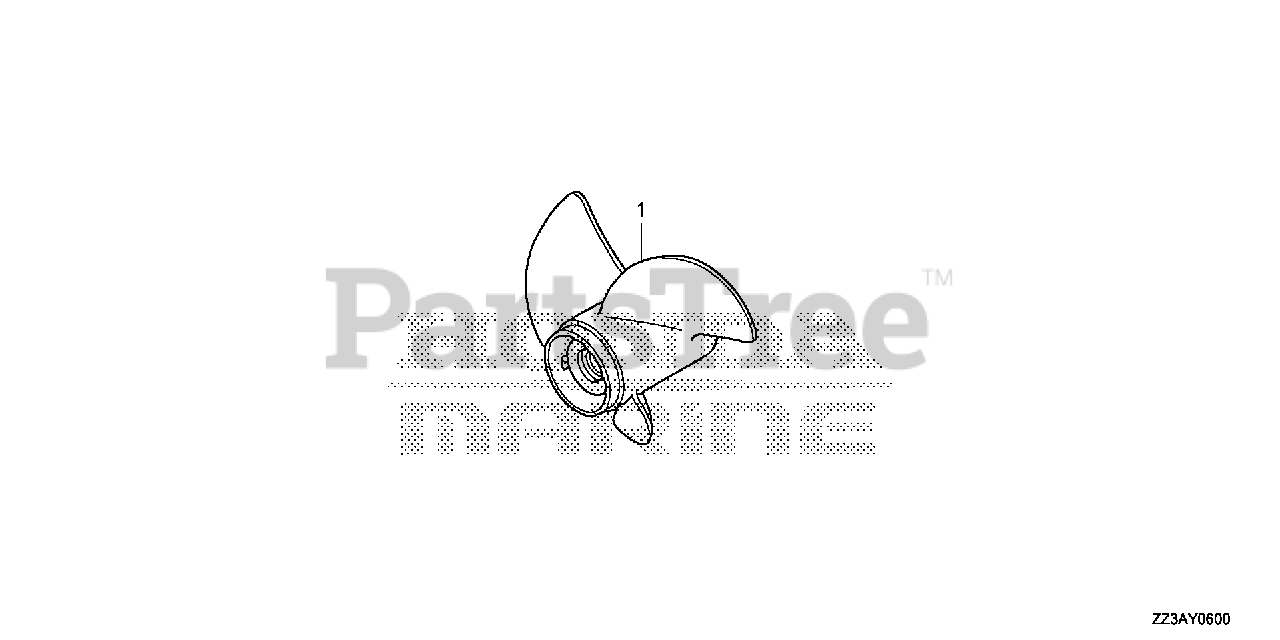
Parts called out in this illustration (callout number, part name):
1	PROPELLER, THREE-BLADE (11-3/8X12) *NH283* (STIN GRAY)
1	PROPELLER, THREE-BLADE (11-1/8X13) *NH283* (STIN GRAY)
1	PROPELLER, THREE-BLADE (11-1/8X14) *NH283* (STIN GRAY)
1	PROPELLER, THREE-BLADE (11X15) *NH283* (STIN GRAY)
1	PROPELLER, THREE-BLADE (11X16) *NH283* (STIN GRAY)
1	PROPELLER, THREE-BLADE (11X17) *NH283* (STIN GRAY)
